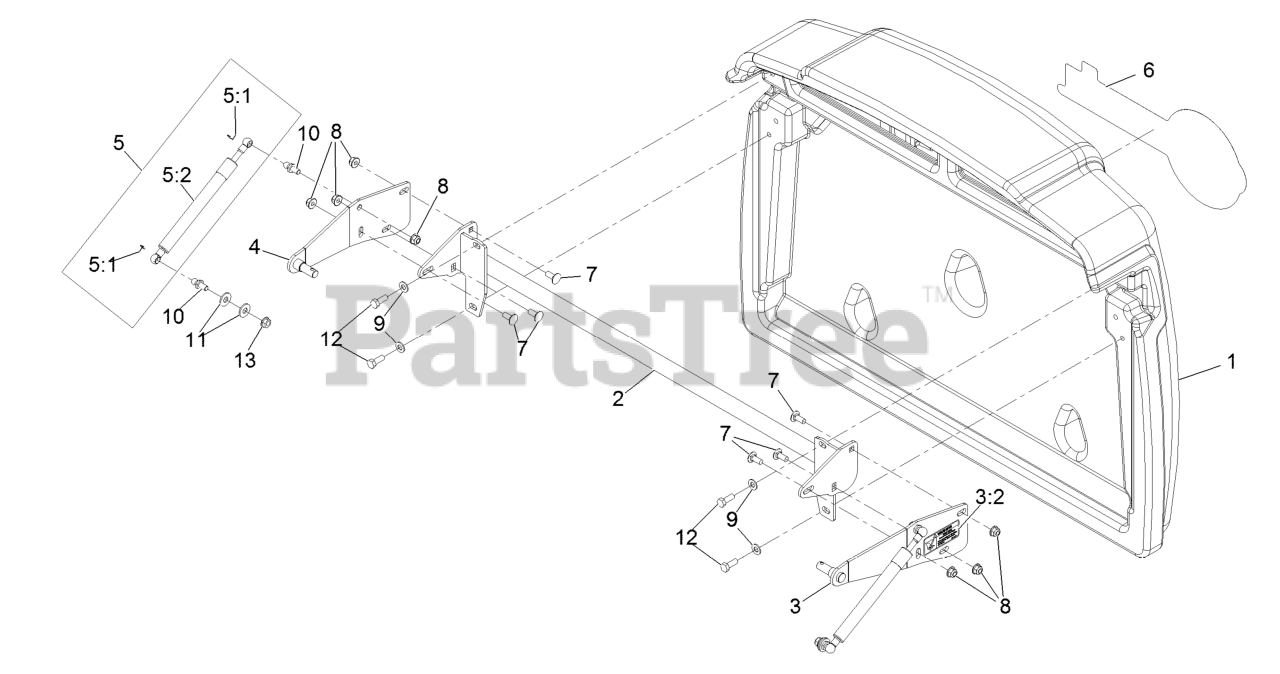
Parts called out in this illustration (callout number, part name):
1	DOOR,HOPPER
2	SUPPORT-DOOR
3	LH DOOR PIVOT ASM
3:2	DECAL-PINCH POINT
4	RH DOOR PIVOT ASM
5	DAMPER KIT
5:1	CLIP-RETAINER
5:2	SHOCK-GAS TENSION
6	DECAL,EXMARK LOGO
7	SCREW-CARR
8	NUT-HF, NI
9	WASHER-PLAIN
10	STUD-BALL
11	WASHER-FLAT
12	SCREW-HH
